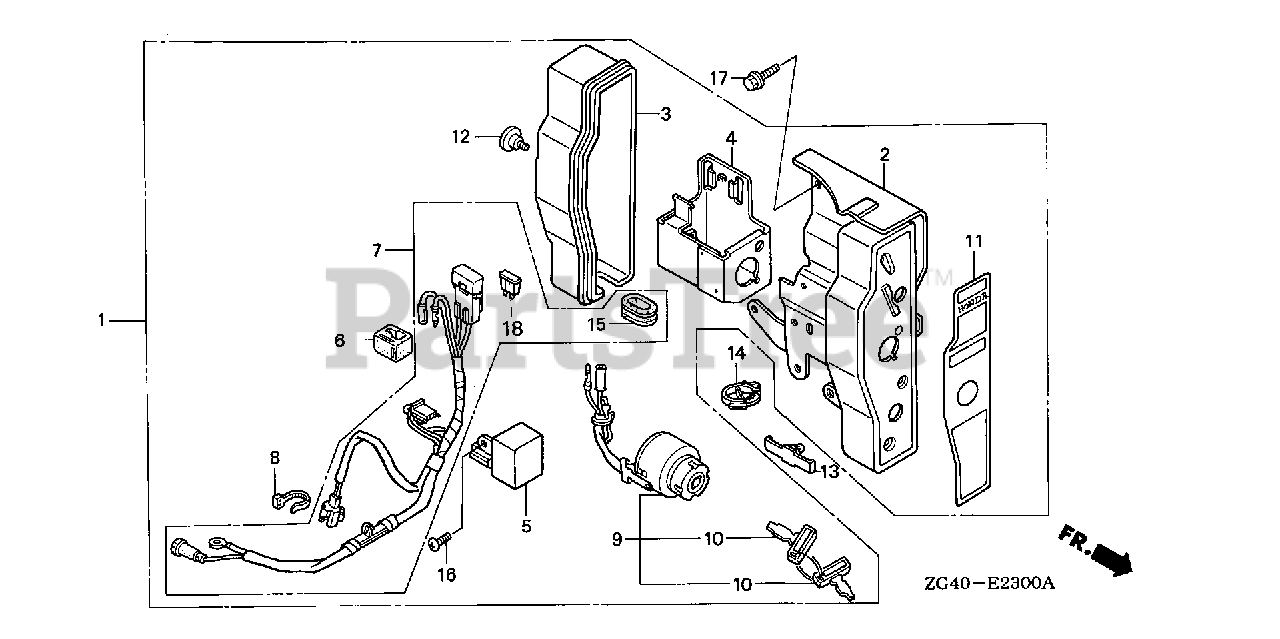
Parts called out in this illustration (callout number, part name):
1	BOX ASSY., CONTROL *NH116M* (EXTERNAL) (URBAN SILVER METALLIC)
2	PANEL, CONTROL *NH116M* (URBAN SILVER METALLIC)
3	CASE, CONTROL
4	BRACKET, CASE MOUNTING
5	RECTIFIER, SILICON
6	SUSPENSION, CONNECTOR
7	WIRE HARNESS ASSY., CONTROL
9	SWITCH ASSY., COMBINATION
10	KEY
11	MARK, CONTROL BOX (EXTERNAL)
12	SCREW, SPECIAL (6X12)
14	CLIP, HARNESS
15	GROMMET, WIRE HARNESS
16	SCREW, PAN (6X12)
17	BOLT, FLANGE (6X16)
18	FUSE, BLADE (15A)
